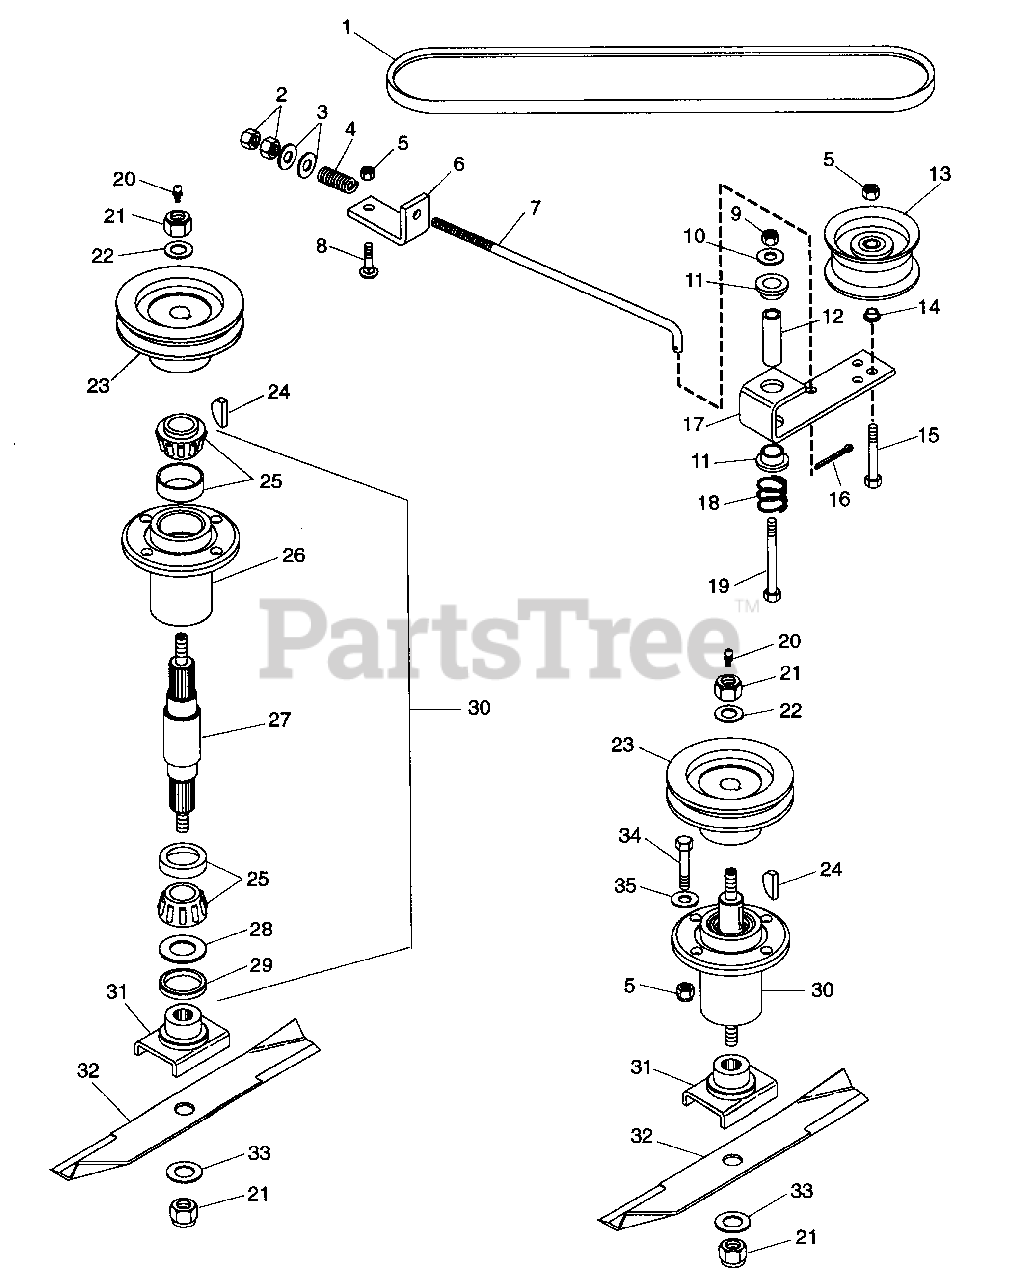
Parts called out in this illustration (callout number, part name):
1	V-Belt A-Rma 37.8 x 33/64
2	Nut-Hex .375-24 Zc
3	Wshr-Fl-Stl .406 x .812 x .065 Pl
4	Sg-Comp .125 x .78 x 1.00
5	Nut-Lk-Nyl .375-16 Pl
6	Brkt, Belt Tensioner
7	Rod, Idler 40 In Mower
8	Blt-Rdhdsqnk .38-16 x 1.00
9	Nut-Lk .50-13 Hex Type N
10	Wshr-Fl-Stl .188 x .438 x .049 N
11	Bshg-Flg .762 x 1.0 x .580 x 1.48 Ny
12	Bush., S.560 x .750 x 2.44 St
13	Idler-Flat 4.00 x .38
14	Bshg-FIg .406 x .88 x .270 x .140
15	Blt-Hex .38-16 x 2.25 Gr 5
16	Pin-Cotr .09 x .75 Pl
17	Arm, Idler Pivot
18	Sg-Comp .085 x 1.00 Wld 36
19	Blt-Hex .50-13 x 3.25 Pl Gr 5
20	Ftg, Lube 1/8
21	Nut-Lk-Nyl.625-11 Pl
22	Wshr-Fl-Stl .687 x 1.312 x .135
23	Sheave, Spindle
24	Kev, Wdrf.25 x 1 Hrd #15
25	Asm, Bearing Cup & Cone
26	Hsg, Bearing
27	Shft, Spindle
28	Wsh-Fl-Stl .97 x 1.865 x.03
29	Sl, Steel
30	Asm, Spindle
31	Wldmt, Blade Crdl
32	Bld, 36" Mower
32	Blade, Sand, 36" Rotary 2 Spndl
33	Wshr-Fl-Stl .656 x 1.312 x .095
34	Blt-Hex .38-16 x 1.25 Pl Gr 5
35	Wshr-Fl-Stl .438 x 1.0 x .083
